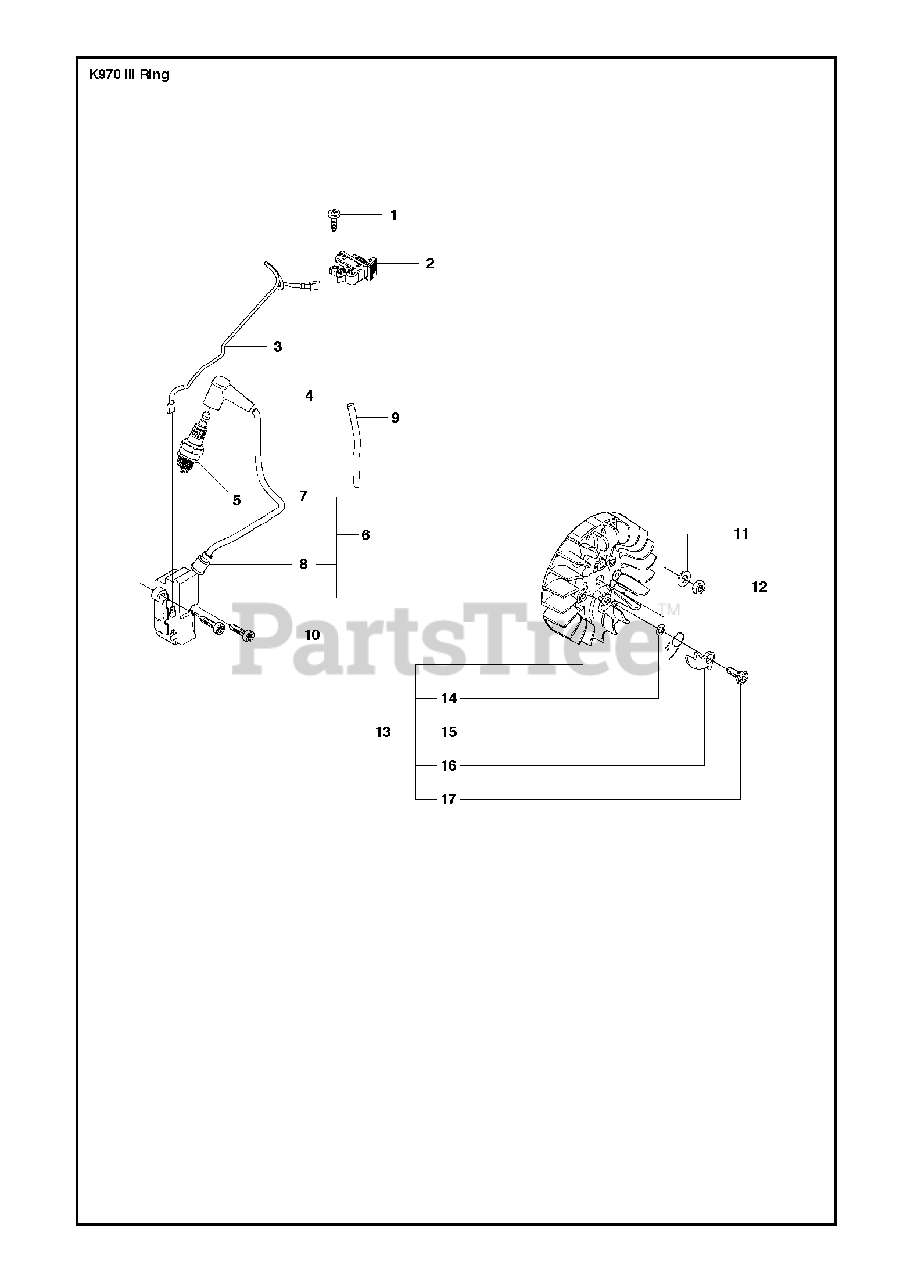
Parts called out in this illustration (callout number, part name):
2	STOP SWITCH
4	SPARK PLUG CAP
5	SPARK PLUGRCJ 6Y
6	IGNITION MODULEIncl. 7 - 8
7	IGNITION CABLE
10	SCREW ITXSCM
13	FLYWHEEL ASSYIncl. 14 - 17
17	SCREW
